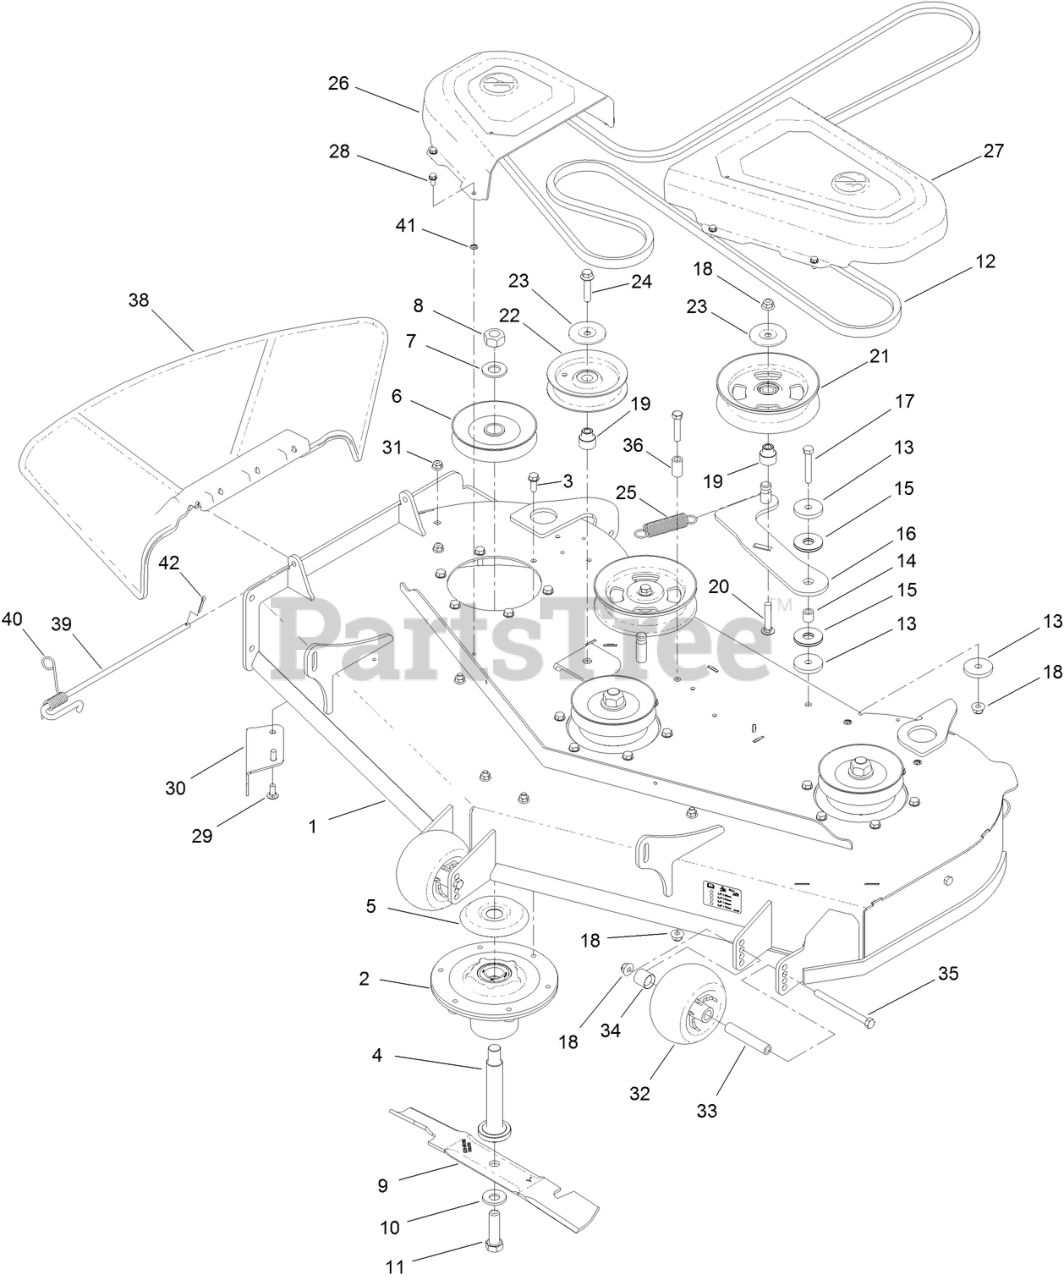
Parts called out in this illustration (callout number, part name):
1	DECK ASM-48"
2	SPINDLE ASM
3	SCREW-TAPTITE
4	SHAFT-SPINDLE
5	SHIELD-BEARING
6	PULLEY
7	WASHER
8	NUT-HEX
9	BLADE - HI FLOW, 16.50 IN
10	WASHER-BELLEVILLE
11	SCREW-BLADE
12	BELT, DECK
13	WASHER-PLAIN
14	BUSHING-IDLER
15	WASHER-FRICTION, COMPOSITE
16	IDLER ARM ASM
17	SCREW-HH
18	NUT-HF, NI
19	BUSHING-IDLER
20	SCREW-CARR
21	PULLEY-IDLER, FLAT
22	PULLEY-IDLER, FLAT
23	SHIELD-DUST
24	SCREW-HHF
25	SPRING-EXTENSION
26	COVER-BELT, RH
27	COVER-BELT, LH
28	SCREW-HWH
29	SCREW-CARR
30	BAFFLE-CUTOFF
31	NUT-HF, NI
32	ROLLER-SCALP, ANTI
33	TUBE-SPANNER
34	SPACER-AXLE, REAR
35	SCREW-HH
36	SPACER-FENDER
38	DEFLECTOR-DISCHARGE
39	PIN-CHUTE
40	SPRING-TORSION
41	NUT-RETAINING
42	PIN-COTTER
